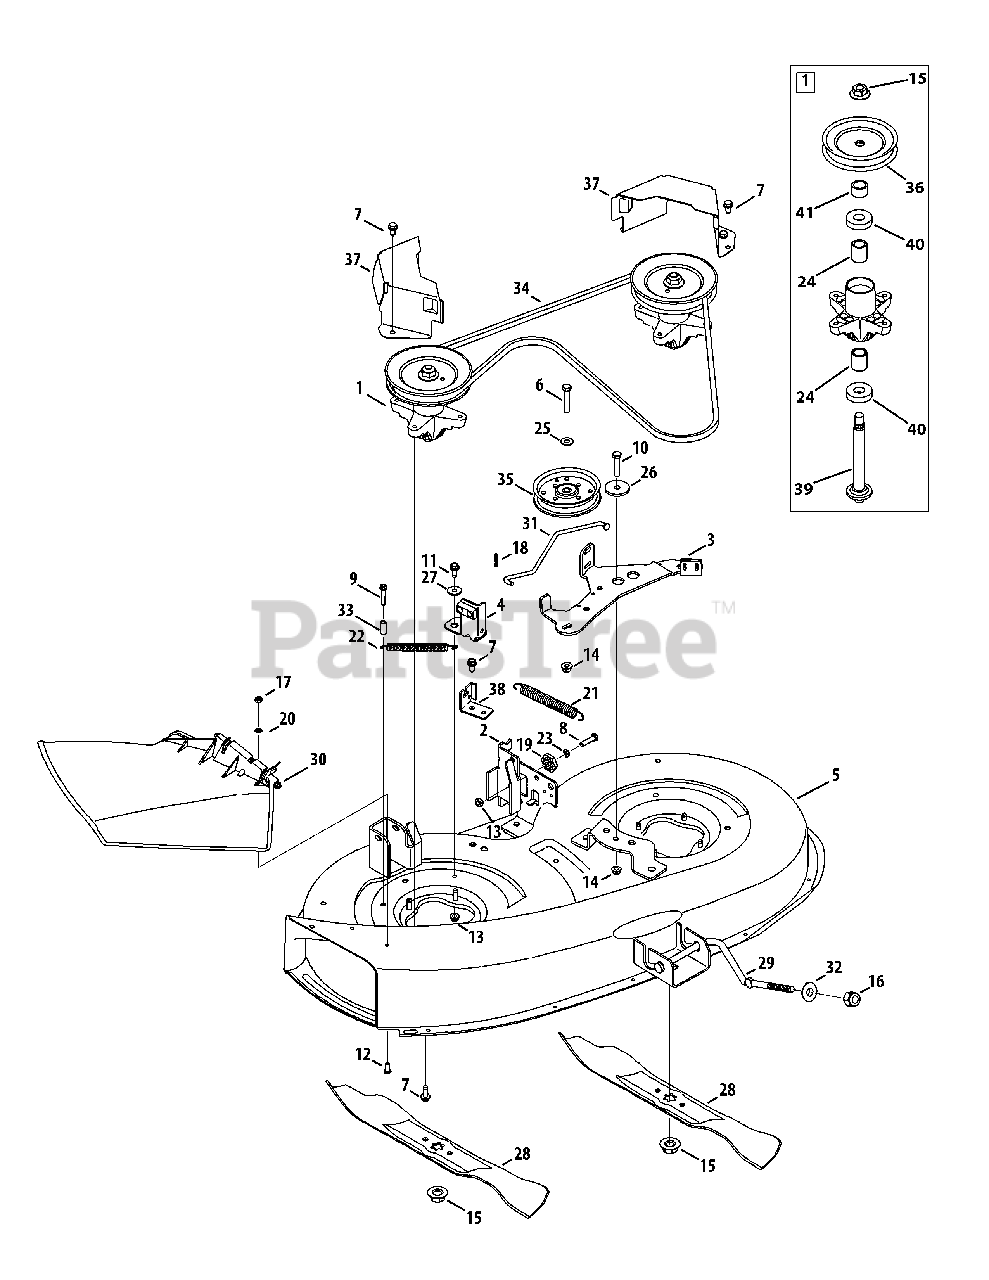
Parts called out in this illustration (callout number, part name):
1	5.75" Pulley Spindle Assembly
2	LH Deck Hanger Bracket
3	Deck Brake Assembly
4	Deck Brake Assembly
5	38" Deck Assembly - Black
5	38" Deck Assembly - Green
6	Hex Screw, 3/8-16 x 1.75
7	Screw, 5/16-18 x .750
8	Hex Screw, 5/16-18 x 1.25
9	Screw, 1/4-20 x 1.50
10	Hex Screw, 3/8-16 x 1.25
11	Hex Screw, 5/16-18 x .75
12	Hex Screw, 1/4-20 x .62
13	Flange Lock Nut, 5/16-18
14	Flange Lock Nut, 3/8-16
15	Flange Nut, 5/8-18
16	Hexlock Nut, 1/2-13
17	Flange Lock Nut, 1/4-20
18	Cotter Pin, .072 Diameter
19	Deck Adjuster Gear
20	Push Nut, .25 x .50
21	Extension Spring, .75 x 6.375
22	Extension Spring, .500 x 6.375
23	Lock Washer, 5/16
24	Spacer, .80 X 1.10 X 1.322 Lg
25	Flat Washer, .406 x .875 x .059
26	Shoulder Spacer, .8840 x .190
27	Shoulder Spacer, .5000 x .1475
28	Blade, 3 in 1
29	38" Front Adjust Deck Rod
30	Chute Assembly
31	38" Brake Control Rod
32	Deck Lift, Pivot Cup
33	Spacer, .260 x .375 x 1.030
34	V Type Belt
35	Idler Pulley
36	Pulley, deck, 5.75 Dia
37	Belt Cover - Black
37	Belt Cover - Green
39	Spindle Shaft, 5.50 Lg
40	Ball Bearing, .787id X 1.85 x.551
41	Spacer, .820x 1.150 X .480 Lg
